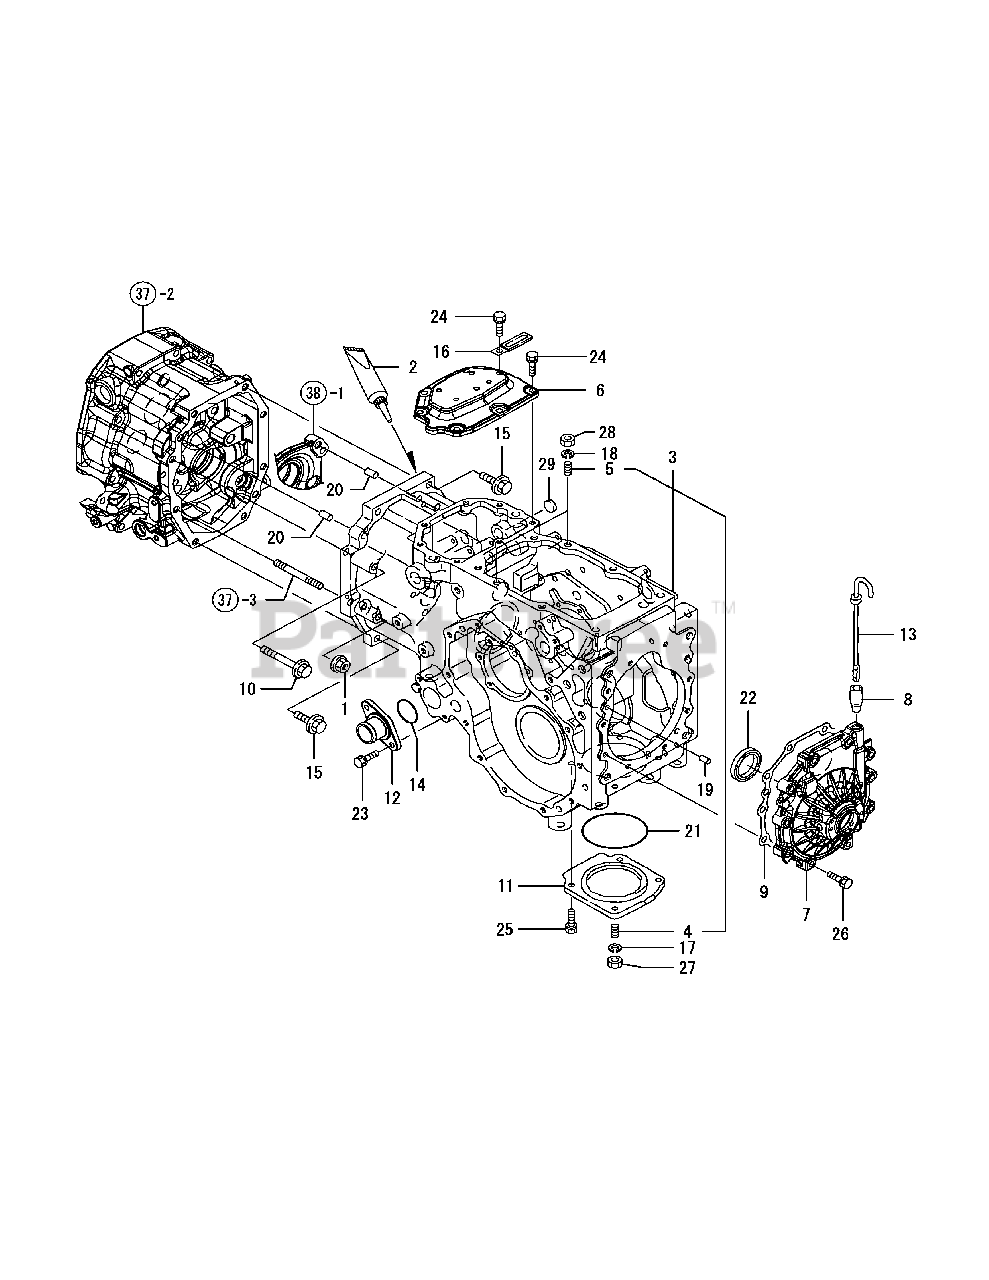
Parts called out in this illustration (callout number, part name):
2	SEALANT, TUBE
3	CASE, MISSION CMP
4	STUD M10X 25 PLATED
5	STUD M10X 25 PLATED
6	COVER, MISSION CASE
7	COVER, REAR COMP.
8	GUIDE, DIPSTICK
9	GASKET, REAR COVER
12	FLANGE, STRAINER
13	GAUGE COMP, OIL
16	CLAMP, WIRE HARNESS
17	SPRING WASHER 10
18	SPRING WASHER 10
19	PARALLEL PIN 8X 16
20	PARALLEL PIN 10X 18
21	O-RING 1A G-95.0
22	SEAL TC40 55 08, OIL
23	BOLT W/WASHER M8X20
24	BOLT W/WASHER M8X20
25	BOLT M10X 30
